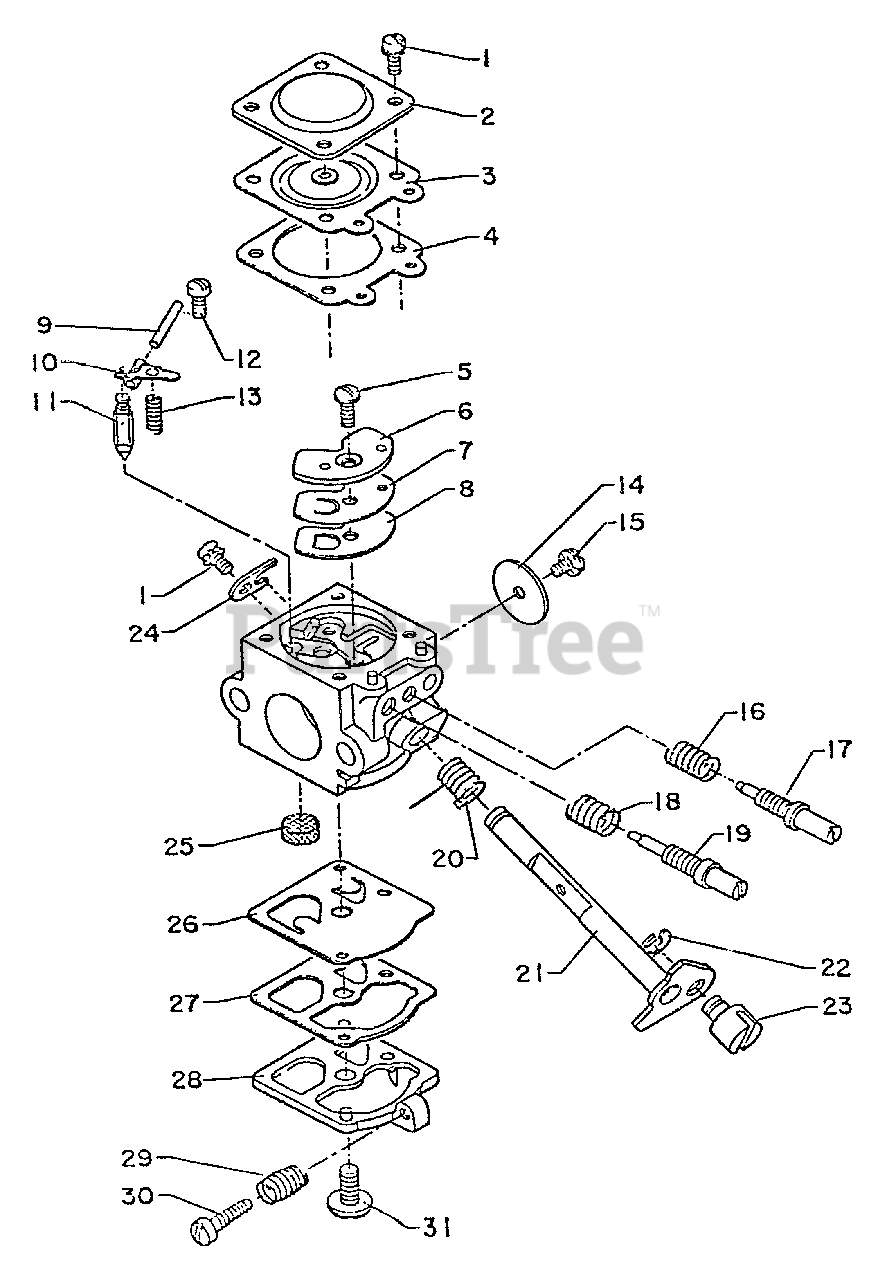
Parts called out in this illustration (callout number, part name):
2	COVER, METERING
3	DIAPHRAGM, METERING
4	GASKET, METERING
5	SCREW, CIRCUIT PLATE
6	PLATE, CIRCUIT
7	VALVE, CHECK
8	GASKET, CIRCUIT PLATE
9	PIN, METERING LEVER
10	LEVER, METERING
11	VALVE, INLET NEEDLE
12	SCREW, METERING LEVER PIN
13	SPRING, METERING LEVER
14	VALVE, THROTTLE
16	SPRING, IDLE ADJUST
17	NEEDLE - LOW SPEED
19	NEEDLE - HIGH SPEED
20	SPRING, THROTTLE RETURN
21	SHAFT, THROTTLE
22	RING, RETAINING
24	CLIP, THROTTLE SHAFT
25	STRAINER
26	DIAPHRAGM, PUMP
27	GASKET, PUMP
28	COVER, PUMP
29	SPRING, IDLE ADJUST
30	SCREW, IDLE ADJUST
31	SCREW, PUMP COVER
